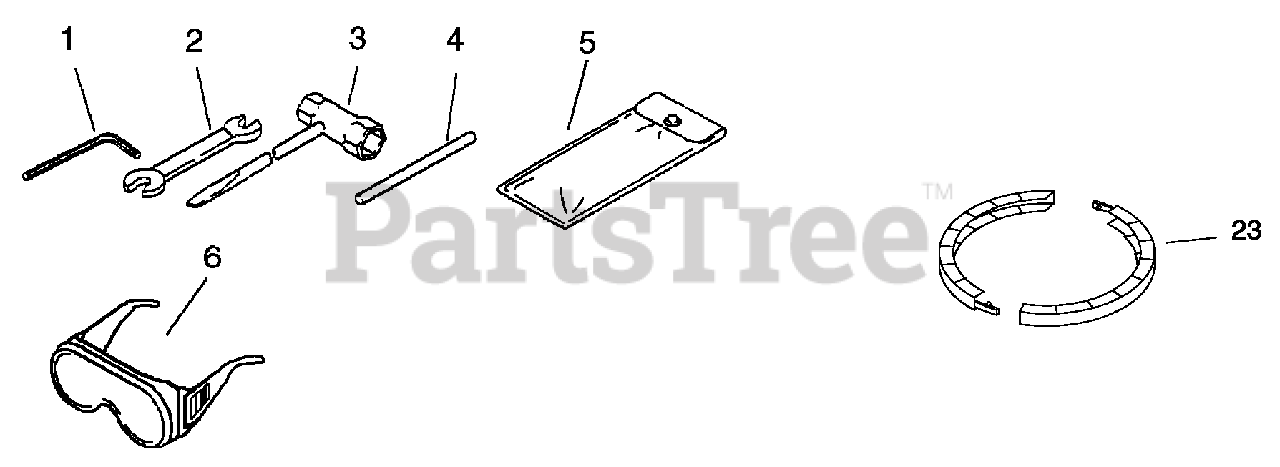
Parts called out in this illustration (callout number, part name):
1	WRENCH, ALLEN 4 MM
2	SPANNER 8×10
3	T-WRENCH 17x-19 L200
4	TOOL, LOCKING 5×120 MM
5	BAG, TOOL
6	GLASSES, SAFETY
23	SCABBARD
